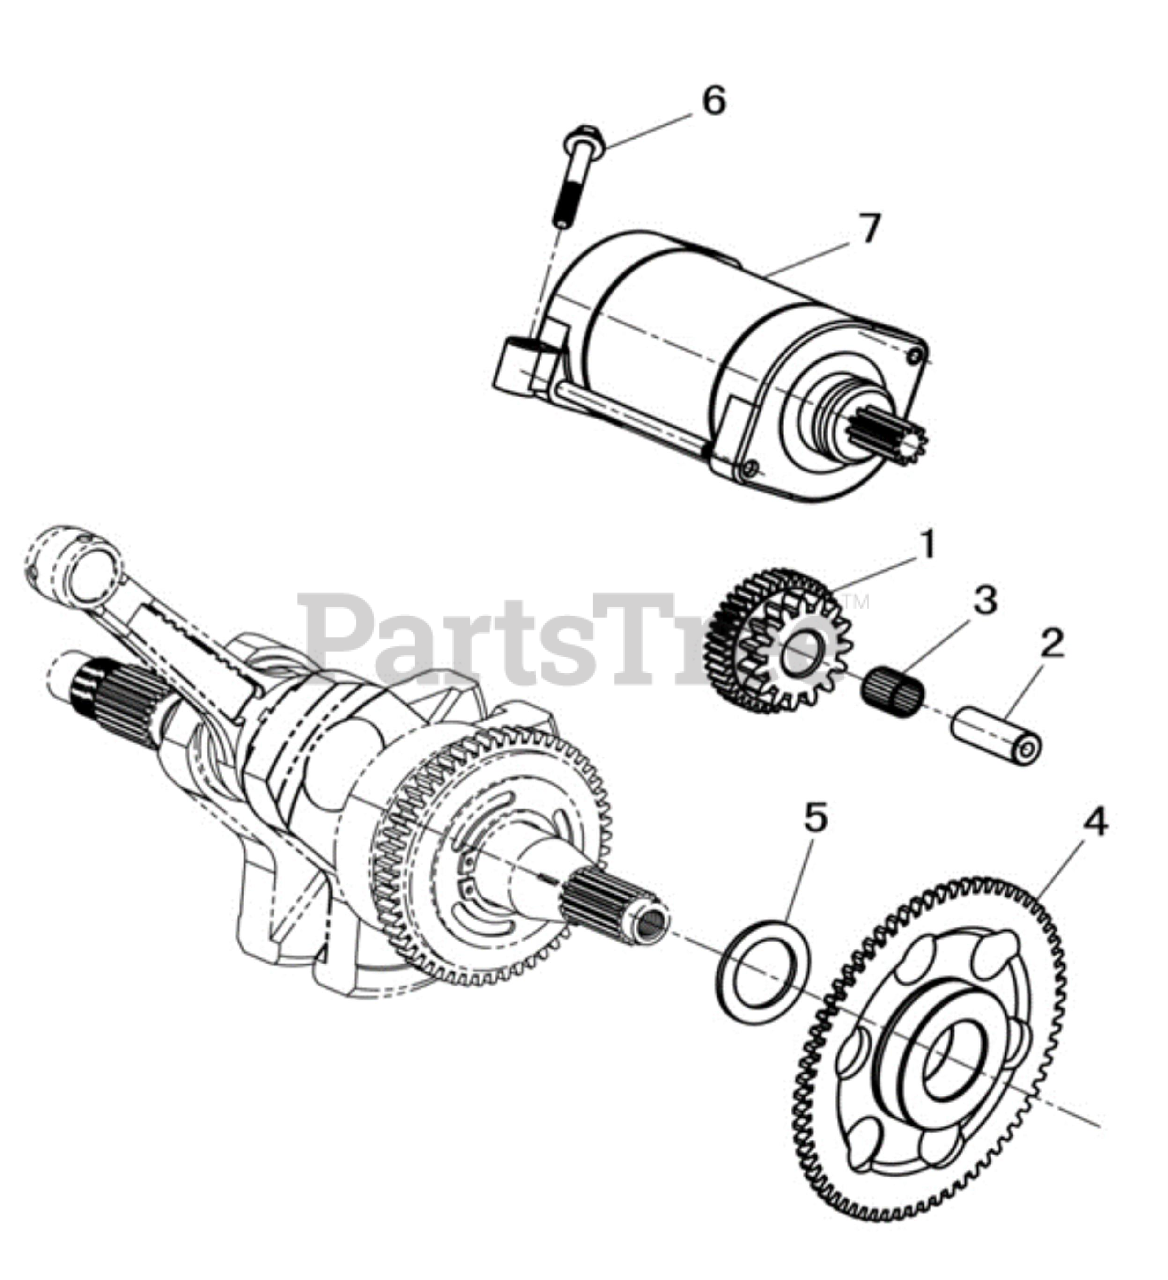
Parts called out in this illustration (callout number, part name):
1	Duplicate Gear
2	Duplicate Gear Shaft
3	Needle Bearing KBK121618
4	Disk Gear Assy
5	Washer 25X39X1
6	Hexagon flange bolts M6X30
7	Starter Motor Assy
